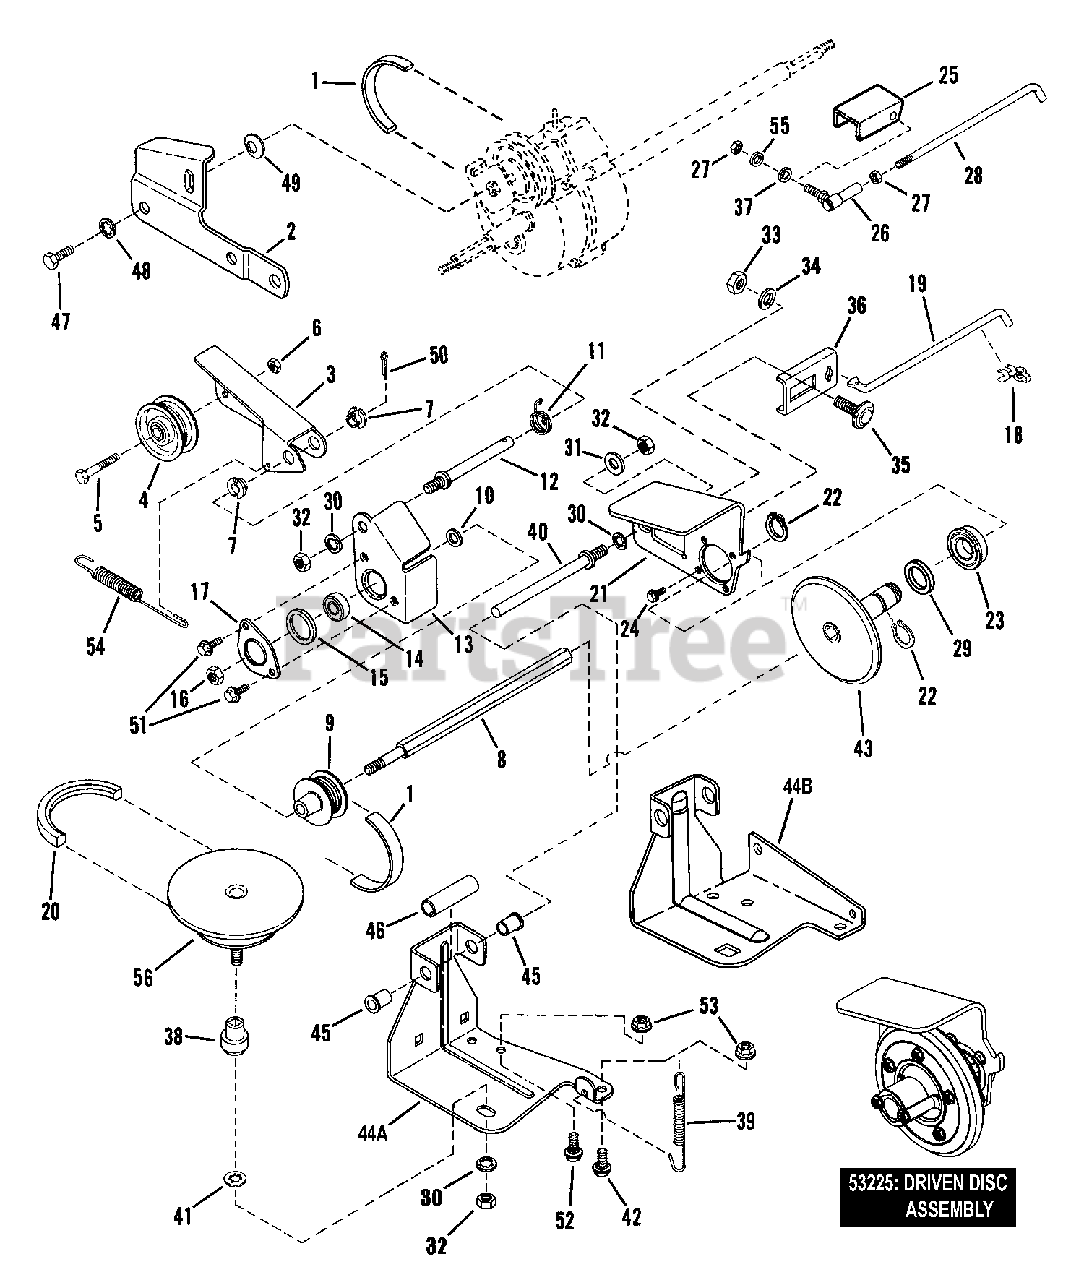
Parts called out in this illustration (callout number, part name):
1	BELT, Poly-Vee
2	LINK, Differential (Commercial)
3	ASSEMBLY, Clutch Idler (Includes #'s 3, 4, 5 & 6)
3	ARM, Clutch Idler
4	PULLEY, Idler
5	SCREW, 1/4-28 x 1-3/8" Hex Head Cap GR5
6	NUT, 1/4-28 Hex Top Lock
7	BUSHING, 3/8" Plastic
8	SHAFT, Hex Drive
9	PULLEY, Poly-V, 2" O.D.
10	WASHER, 3/8" Flat
11	SPRING, Idler, Torsion
12	STUD, Idler (3/8-24 thread)
13	HOLDER, Half
14	BALL BEARING, .38 I.D. Spherical O.D.
15	O-RING
16	NUT, 3/8-24 Hex Center Lock GR5 or B
17	HOLDER, Half
18	CLIP, Transfer Rod 1/4"
19	ROD, Transfer
20	BELT, Engine Drive 3L (Stretch)
21	THRUST PLATE, Short
22	RING, 5/8" External Retaining
23	BALL BEARING, 3/4" I.D.
24	HWST, #10F X1/4 BZ
25	SHIELD, Hex Shaft
26	BALL JOINT, 1/4-28
27	NUT, 1/4-28 Hex
28	LINK, Transfer
28	ASSY., Transfer Rod (Includes #'s 26, 27 & 28)
29	WASHER, 3/4" Shim
30	WASHER, 3/8" Internal Tooth Lock
31	WASHER, 3/8" Flat
32	NUT, 3/8-24 Hex
33	NUT, 5/16-18 Hex, GR5
34	WASHER, 5/16" Split Lock
35	BOLT, 5/16-18 x 3/4" Short Neck Carriage GR5
36	CONNECTOR, Transfer Rod
37	WASHER, .28 x .63 x .06 Flat
38	BUSHING
39	SPRING, Wheel Drive
40	GUIDE, Thrust Plate (3/8-24 thread)
41	RETAINER, 3/8" Bolt
42	BOLT, 5/16-18 x 5/8" Short Neck Carriage GR5
43	DISC, Driven (Cantilever)
44A	ASSY, Deck Bracket (Includes items 44A & 45)
44A	BRACKET, Deck
44B	BRACKET, Deck, Painted Black Texture
45	BUSHING, 3/8" Plastic
46	SPACER
47	SCREW, 5/16-18 x 1/2" Hex Head Cap, GR5
48	WASHER, 5/16" Internal Tooth Lock
49	WASHER, .44 x .78 x .025 Curved
50	PIN, 3/32 x 1/2" Cotter
51	SCREW, 1/4-20 x 1/2" Hex Washer Self-Tap
52	BOLT, 5/16-18 x 1/2" Short Neck Carriage GR5
53	NUT, 5/16-18 Hex Flange Lock, GR 5
54	SPRING, Clutch
55	WASHER, 1/4" Internal Tooth Lock
56	KIT, Drive Disc Assembly
53225	ASSEMBLY, Driven Disc (Alternate to #'s 21, 22, 23, 24, 29 & 43)
